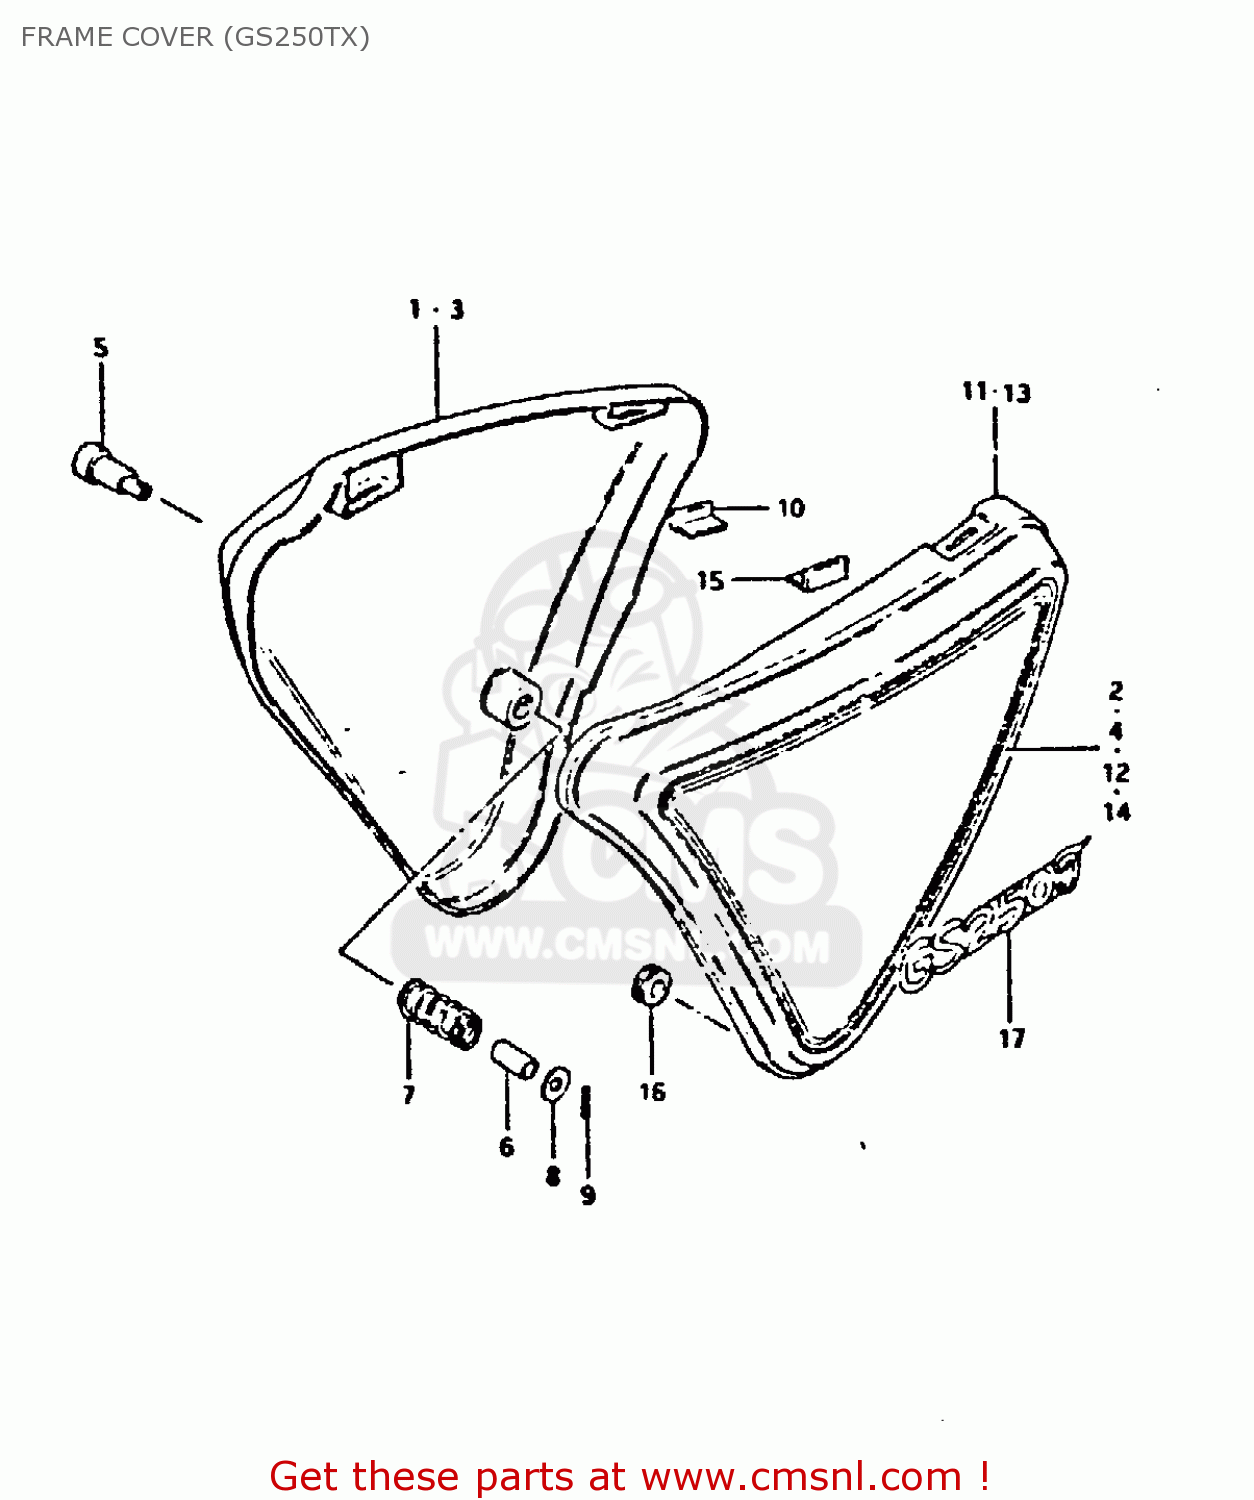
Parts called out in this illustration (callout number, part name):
1	COVER,FRAME,RIGHT
2	TAPE SET,FRAME COVER,RIGHT
3	COVER,FRAME,RIGHT
4	TAPE SET,FRAME COVER
5	KNOB, FRAME COVER RH
6	SPACER(14.9X17.3X13.5)
7	SPRING
8	WASHER (6.5X24X1.6)
9	PIN,SPRING(2.5X18)
10	CUSHION,FRAME COVER
11	COVER,FRAME,LEFT
12	TAPE SET,FRAME COVER
13	COVER,FRAME,LEFT
14	TAPE SET,FRAME COVER
15	CUSHION,FRAME COVER
16	CUSHION
17	EMBLEM,FRAME COVER
